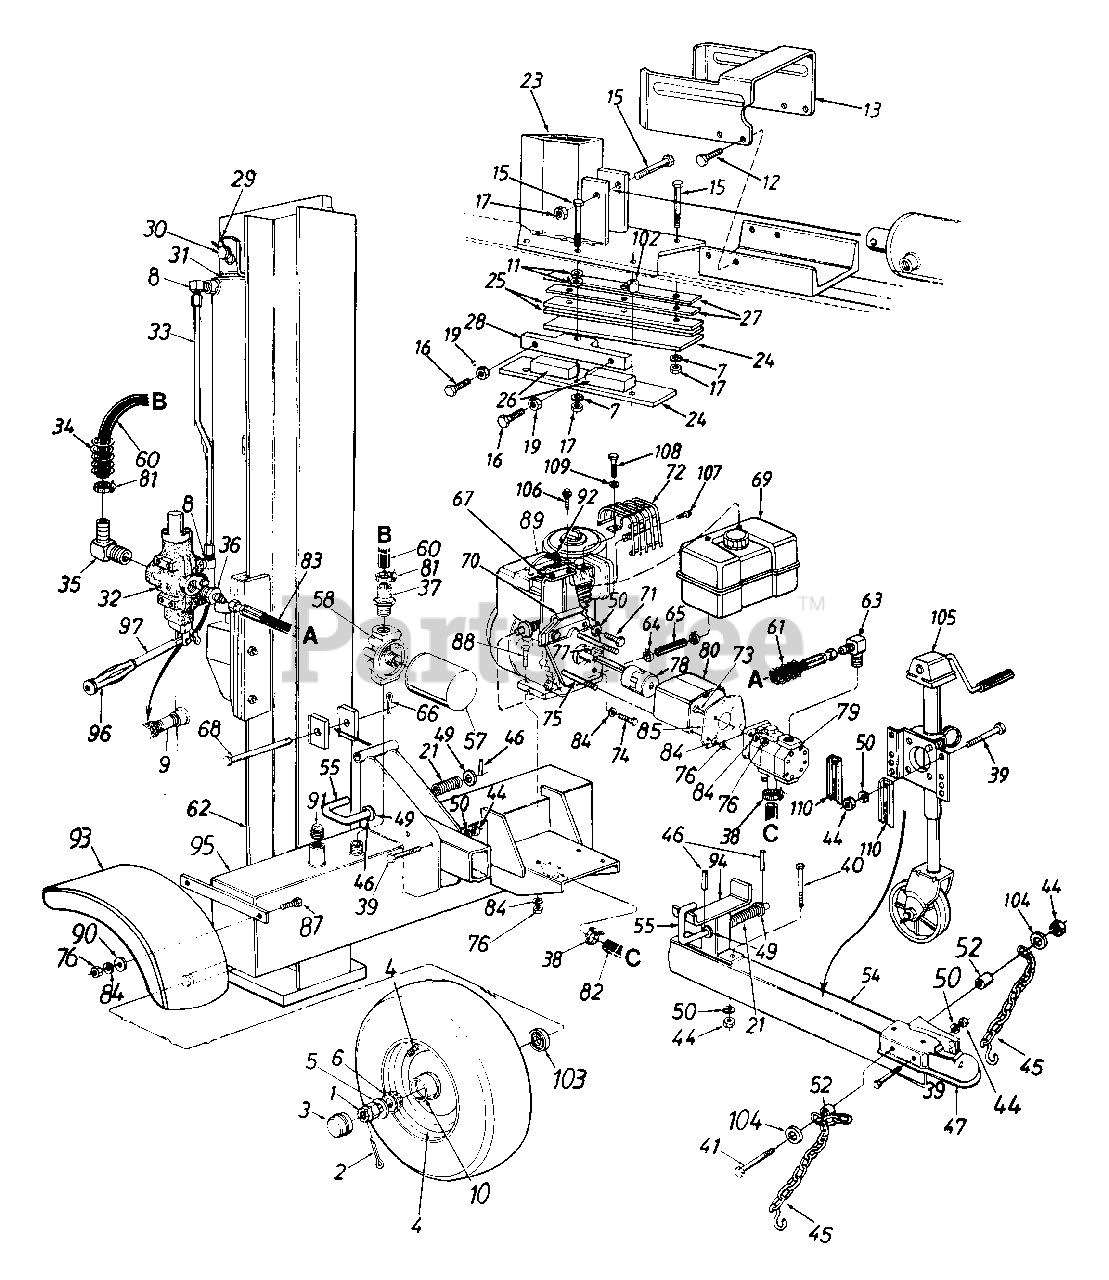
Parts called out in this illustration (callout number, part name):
1	Slotted Nut 3/4-16 Thd
2	Cotter Pin 5/32" Dia
5	Fl-Wash. .76" I.D. x 1.5" O.D
6	Bearing Cone
7	L-Wash. 1/2" I.D.
8	90ø Solid Male Adaptor
9	Pipe Nipple 1/2 NPT
10	Bearing Cup
11	Fl-Wash. .531" I.D. x .94" O.D.
12	Hex Cap Scr. 3/8-16 x 1" Lg.
15	Hex Bolt 1/2-20 x 2.75" Lg (Grade 8)
16	Hex Bolt 3/8-24 x 1.5" Lg.
17	Hex L-Nut 1/2-20 Thd.
19	Hex Jam Nut 3/8-24 Thd (Grade 5)
21	Comp. Spring 4" Lg.
26	Adjustable Gib
29	External Cotter Pin
30	Cylinder Mounting Pin
33	Metal Pressure Tube
34	Hose Guard
35	Return Elbow
37	3/4" Hose Barb.
38	Hose Clamp 1.5" O.D
39	Hex Bolt 3/8-16 x 3" Lg (Grade 8)
40	Hex Bolt 3/8-16 x 4.75" Lg.
41	Hex Bolt 3/8-16 x 4.25" Lg.
44	Hex Nut 3/8-16 Thd.
45	Chain - Tow Hitch
47	Hitch Coupler
49	Fl-Wash. .635" I.D. x .93" O.D.
50	L-Wash. 3/8" I.D.
52	Spacer .445" Lg.
57	Filter Element
58	Filter Head
60	Return Hose 3/4" I.D. x .44" Lg
61	Hose Guard
64	Hose Clamp 37" Dia
65	Fuel Line (6" Lg.)
66	Cotter Pin 1/8" Dia.
67	Tank Mtg Brkt
68	Hinge Pin 1/2 x 4.8" Lg
69	Fuel Tank Ass'y
70	Support Brkt
71	Hex Bolt 3/8-16 x 1" Lg.
72	Muffler Guard
73	Hex Bolt 5/16-24 x 1" Lg
74	Hex Bolt 5/16-24 x 62" Lg
75	Hex Bolt 5/16-24 x 5.25" Lg.
76	Hex Nut 5/16-24 Thd
77	Sq -Key 1/4" x 2" Lg
78	Flexible Coupling
79	Gear Pump
80	Coupling Shield
81	Hose Clamp 5/8"
82	Suction Hose 1" I.D.
83	High Pressure Hydraulic Hose 48"
84	L-Wash 5/16" I.D.
87	Hex Bolt 5/16-24 x 75" Lg
88	Hex Bolt 5/16-24 x 1.75" Lg
89	Engine
90	Fl-Wash .344" I.D. x .875" O.D.
91	L-Vent Pipe Plug
92	Spark Plug Boot
97	Control Handle
102	Spacer 1/2" I.D. x .86" Lg.
103	Bearing Seal Only
104	Fl-Wash 3/8" I.D. x .87" O.D.
105	Jack Stand
106	Hex AB-Tap Scr 1/4 x 3/4" Lg.
107	Hex Wash Hd Scr #8 x 5" Lg.
108	Hex Bolt 1/4-20 x 5" Lg.
109	Fl-Wash 25" I.D. x .5" O.D.
